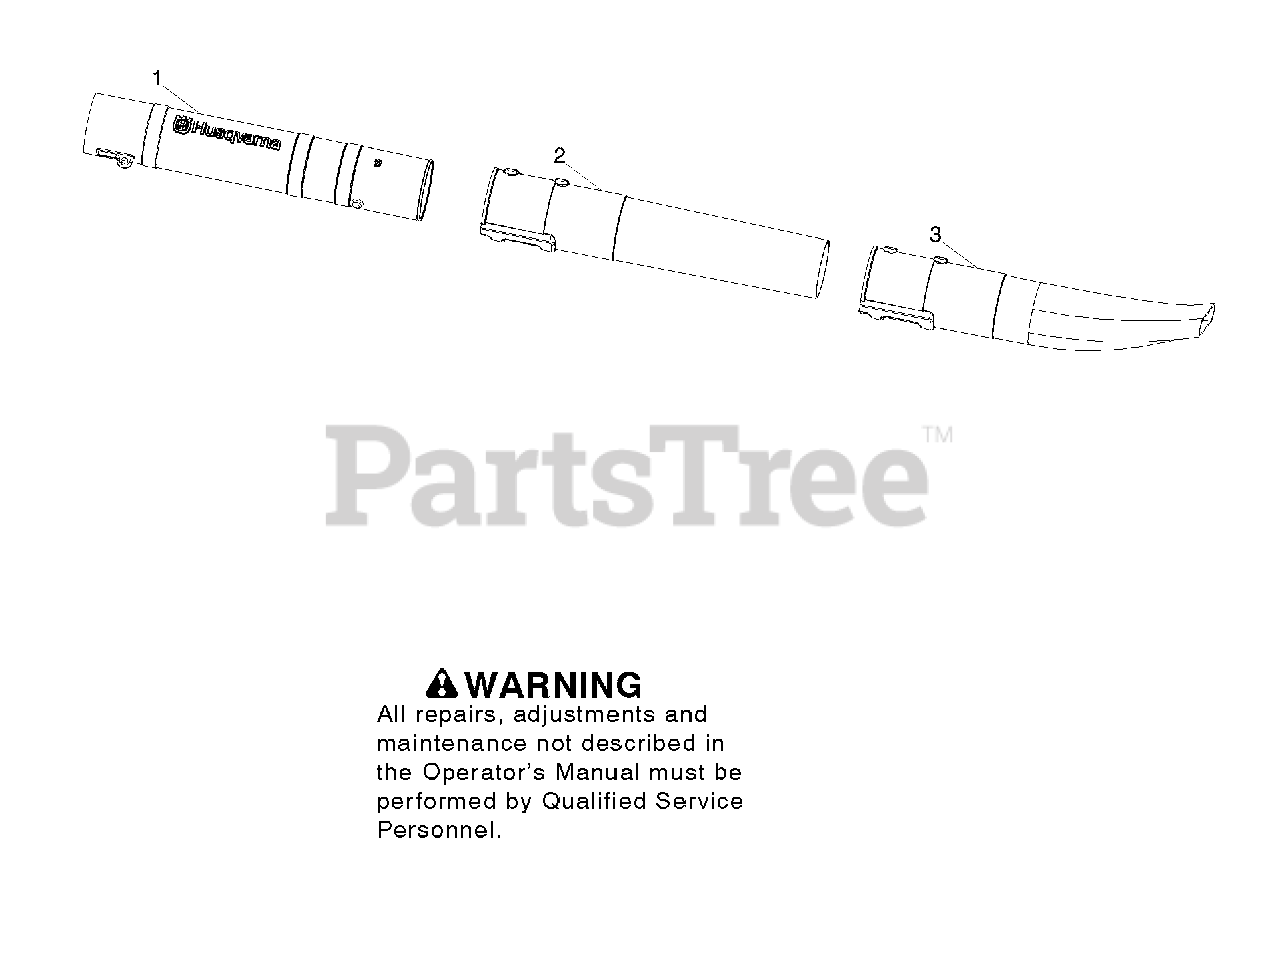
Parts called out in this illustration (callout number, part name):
1	Assy - Tube - Upper Blower w/barrier
2	Tube - Lower Blower
3	Flare - Lower Blower tube
